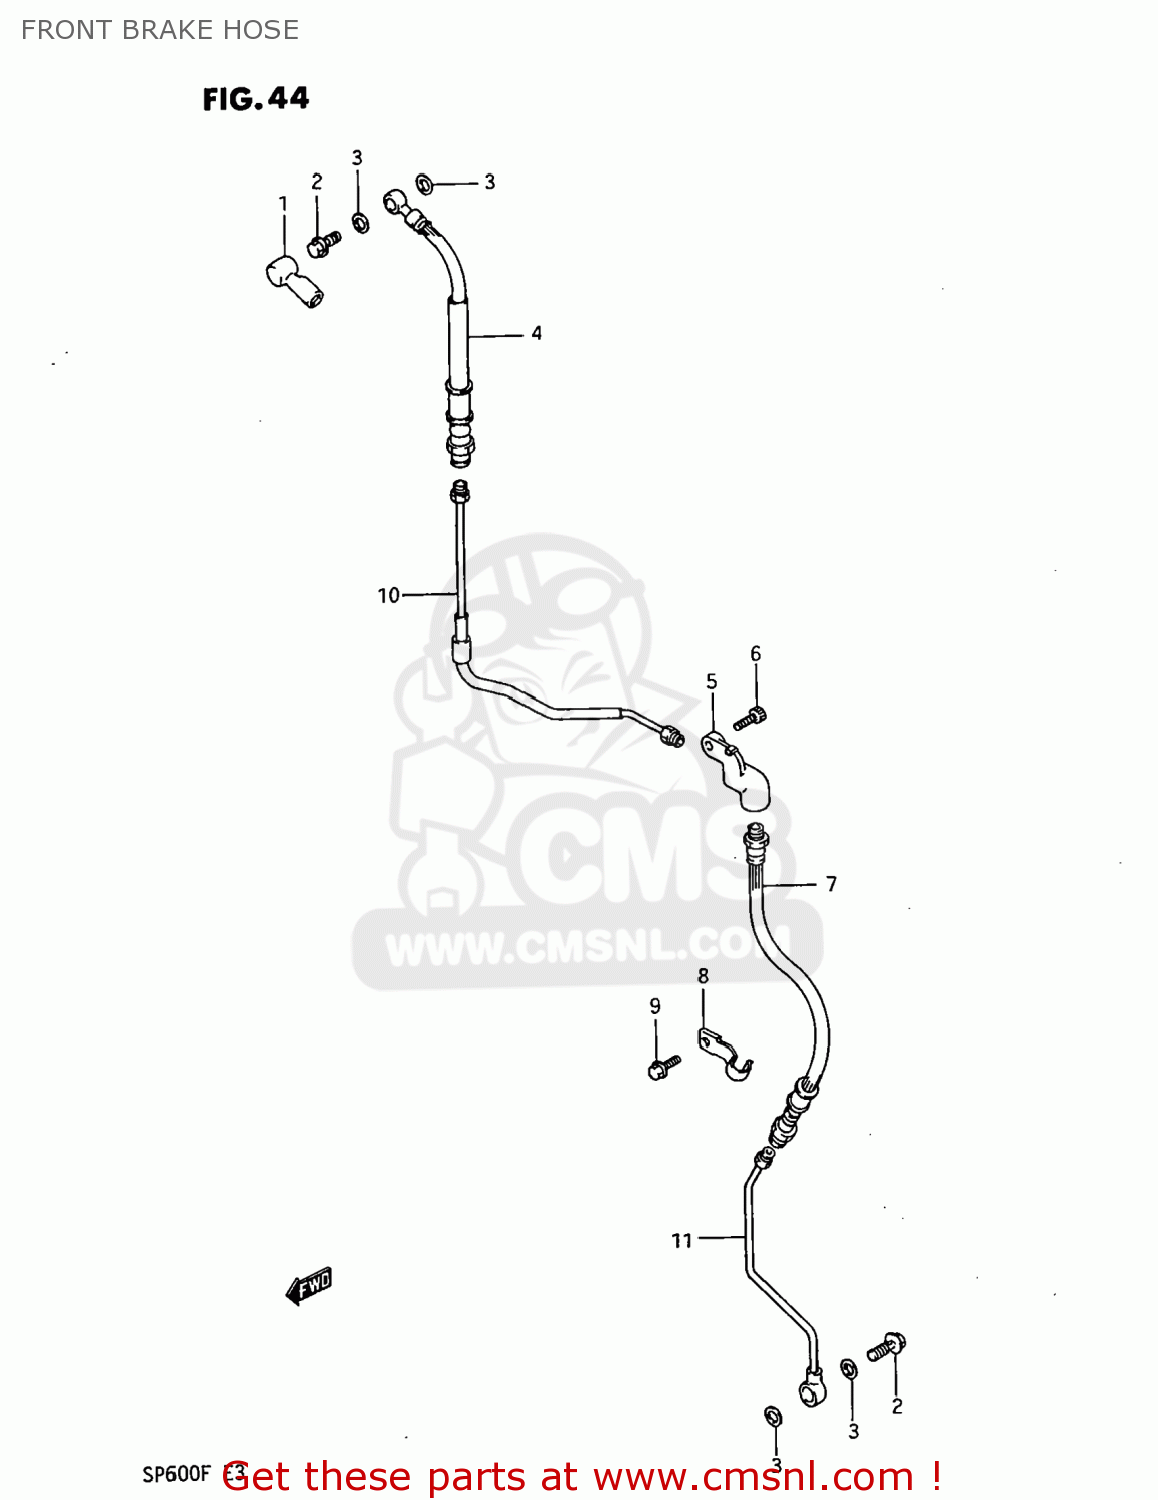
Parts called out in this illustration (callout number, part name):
1	BOOT,MASTER CYLINDER
2	BOLT,UNION
3	WASHER(10X15X1.5)
4	HOSE,FRONT BRAKE NO.1
5	JOINT,FRONT BRAKE
6	BOLT
7	HOSE,FR BRAKE NO.2
8	CLAMP,FRONT BRAKE HOSE
9	BOLT
10	PIPE,FRONT BRAKE NO.1
11	PIPE,FRONT BRAKE NO.2
